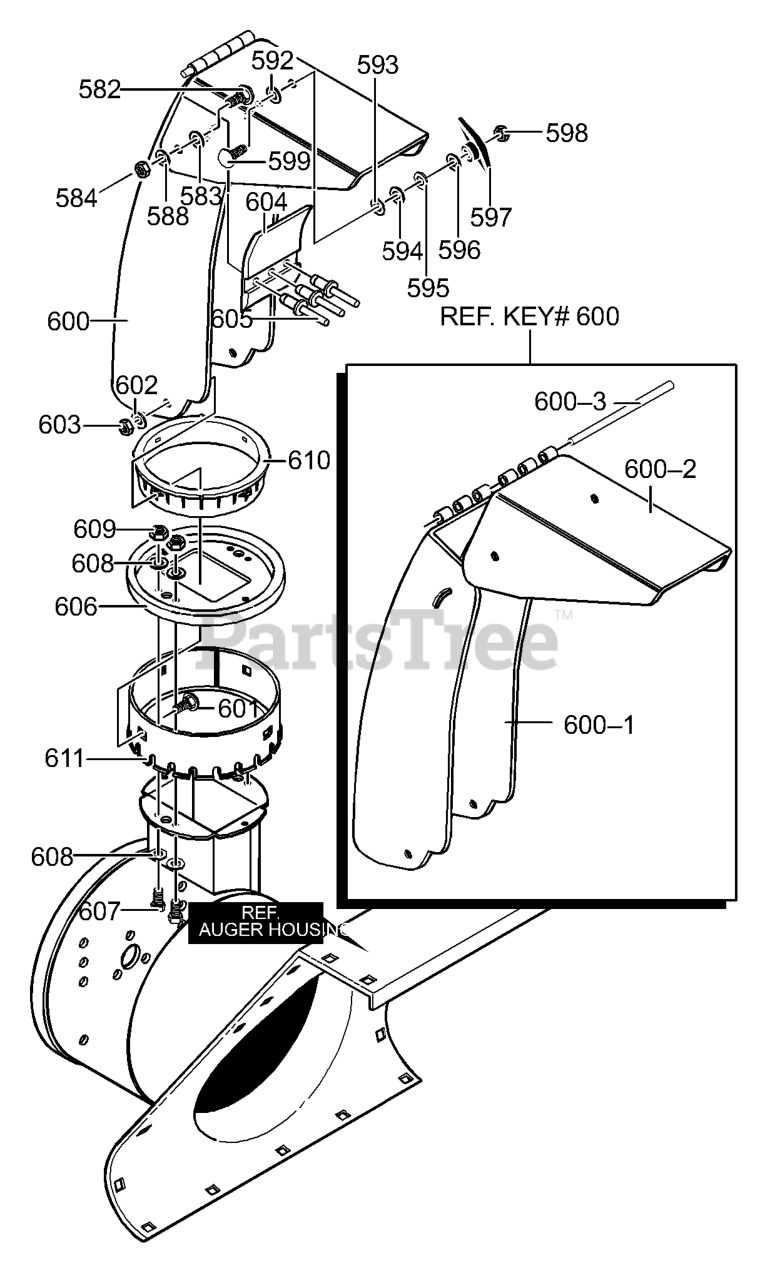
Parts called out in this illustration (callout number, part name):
583	WASHER, PLASTIC
584	NUT
588	WASHER, PLASTIC
592	WASHER, PLASTIC
593	WASHER, PLASTIC
594	WASHER, FLAT
595	WASHER
596	WASHER, FLAT
597	T-KNOB
598	NUT
599	BOLT, CARRIAGE
600	CHUTE, ASSEMBLY WITH GUARD
600-1	CHUTE, LOWER
600-2	UPPER, CHUTE
600-3	PIN, HINGE
601	BOLT, 5/16-18X1.00
602	FLATWASHER
603	NUT, 5/16-18
606	COLLAR, CHUTE
607	SCREW, 1/4-20X .75
608	FLATWASHER
609	NUT, 1/4-20 HEX NYLOCK
610	RETAINER, RING INNER
611	RETAINER, RING OUTER
